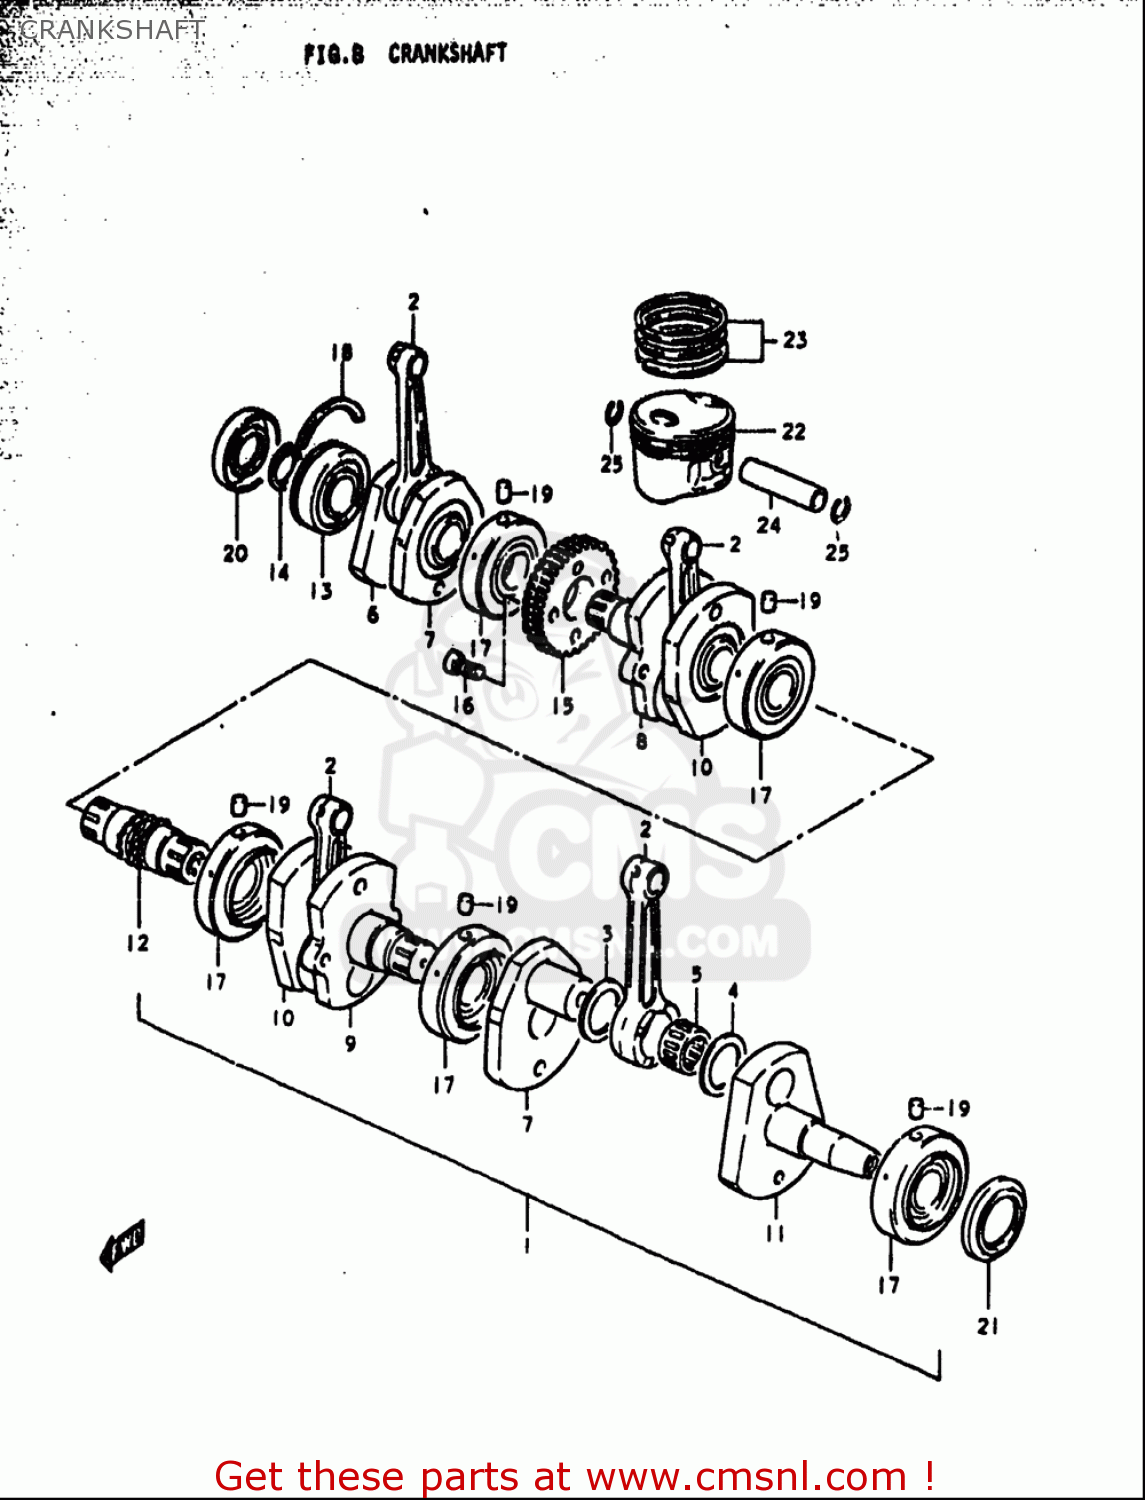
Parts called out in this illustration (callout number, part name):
2	ROD,CONNECTING
5	BEARING(29X39X20)
13	BEARING(30X72X19)
14	CIRCLIP
16	BOLT
17	BEARING(32X72X21)
18	C RING
19	PIN
20	SEAL,OIL(30X72X11)
21	SEAL,OIL(47.3X60X6.5)
22	PISTON
23	RING SET,PISTON
24	PIN,PISTON (18MM)
25	CIRCLIP,PISTON PIN
